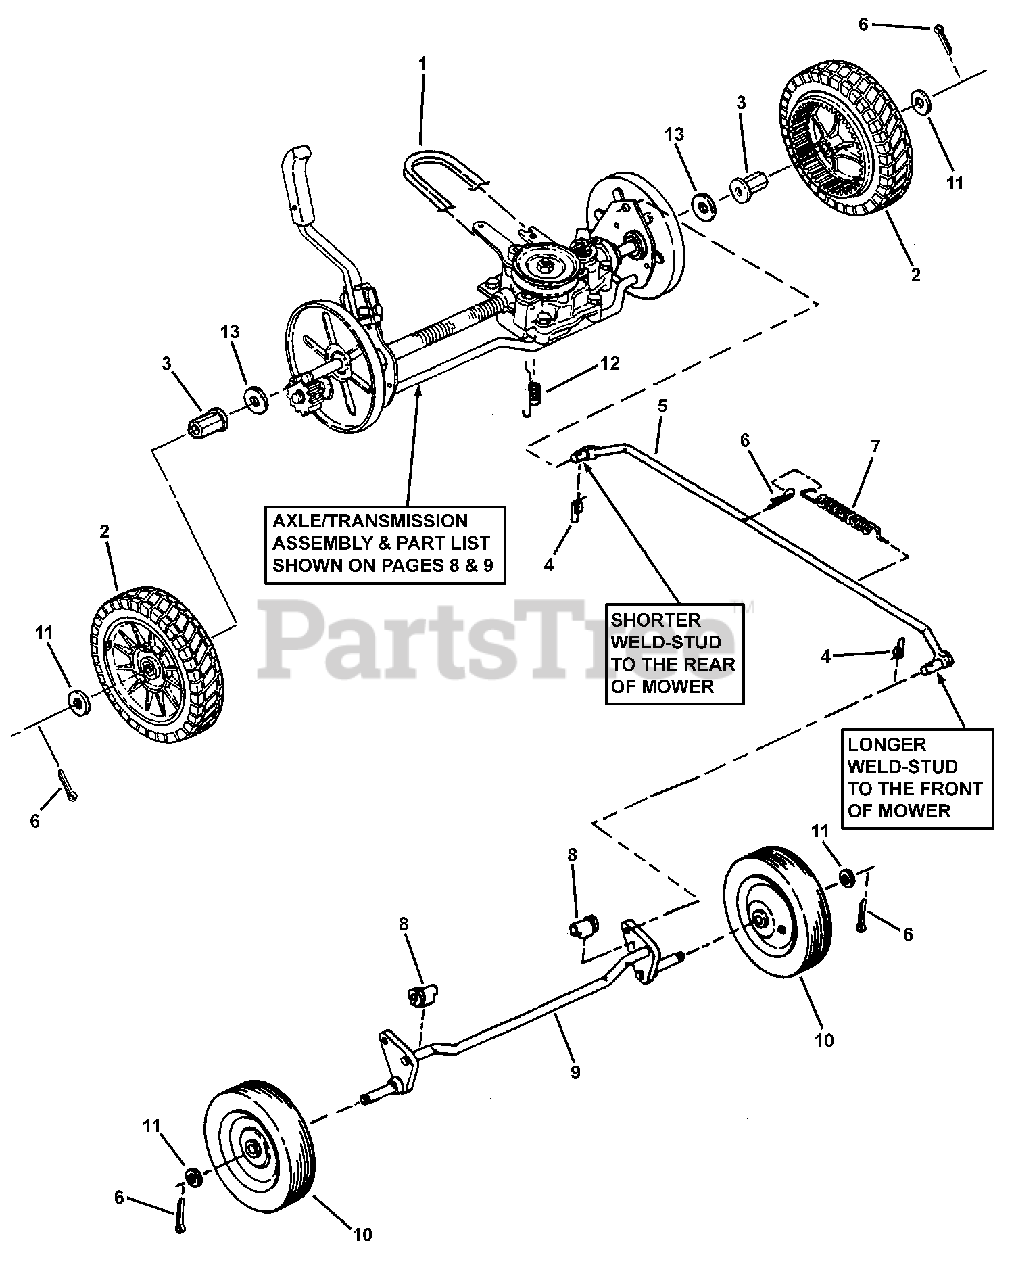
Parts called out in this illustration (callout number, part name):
1	BELT, Traction Drive, Sect. 3L, 33.20" effective length
2	WHEEL, 9.0 x 2.0 (Rear Drive)
3	BUSHING, Wheel
4	COTTER PIN, 3/8" Self Locking
5	WELDMENT, Tie Bar
6	COTTER PIN, 1/8 x 3/4"
7	SPRING, Tie Bar
8	BUSHING, Front Axle
9	WELDMENT, Front Axle
10	WHEEL, 8.0 x 2.0 (Front)
11	WASHER, 1/2" Flat
12	SPRING, Clutch
13	WASHER, 17/32" Flat
